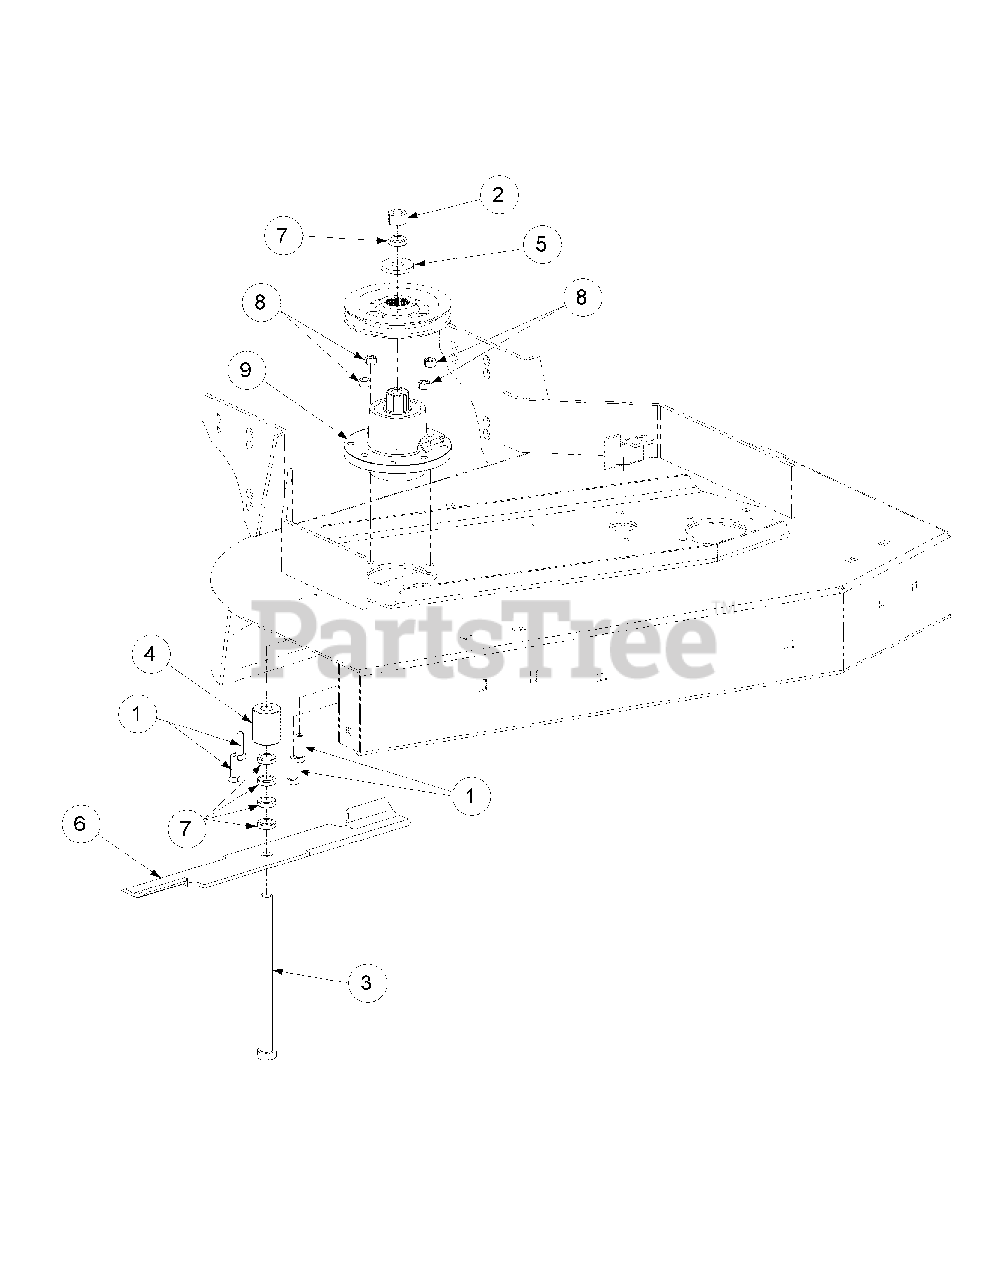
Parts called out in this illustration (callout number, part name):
1	Hex Cap Screw, 3/8-16 x 1-1/2
2	Hex Nut, 5/8-11
3	Hex Cap Screw, 5/8-11 x 9
4	Blade Spacer, .630 x 1.500 x 1.850
5	Flat Washer, .656 ID x 1.313 OD
6	18" Rotary Blade
7	Blade Spacer, 5/8 ID, 1/4 Thick
8	Hex Nut Flange Lock, 3/8-16
9	Spindle Assembly
9	Grease Fitting, 1/4-28 x 1.609
